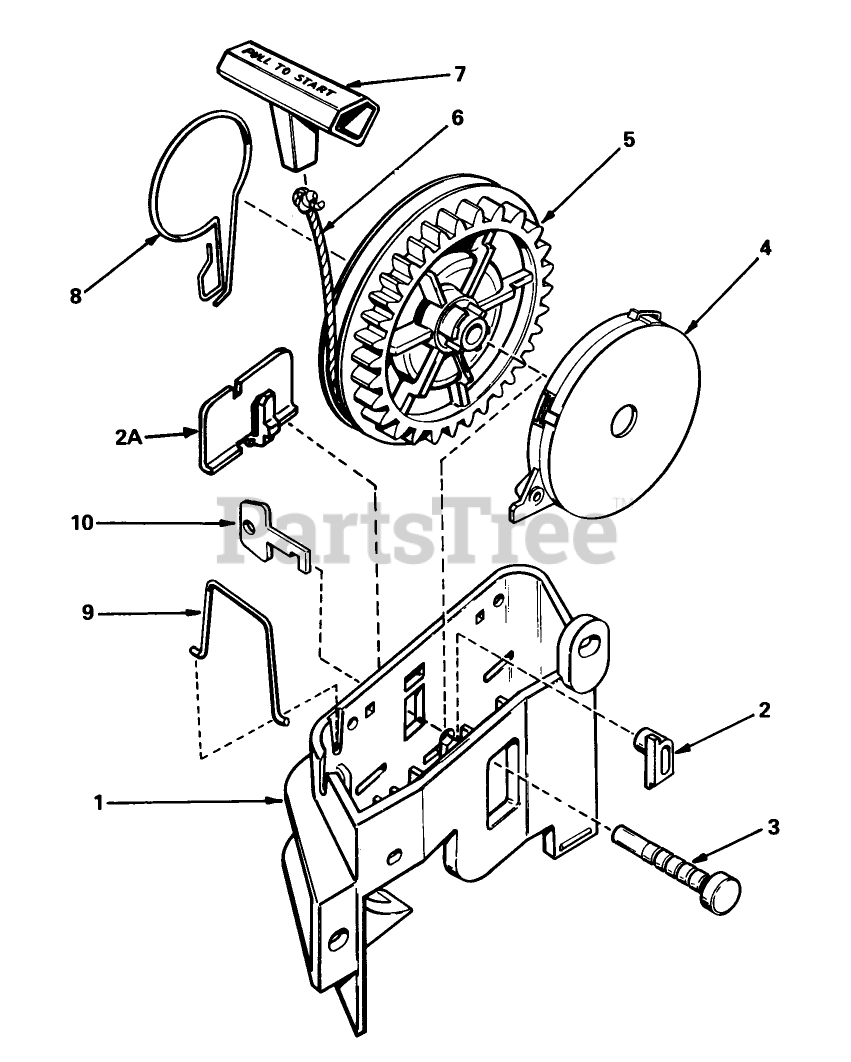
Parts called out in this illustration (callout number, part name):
1	Bracket Starter
2	Pawl, Locking Not used on all engine models)
2A	Clip, Starter Bracket (Used On Starters Not Equipped With Pawl, Ref. No. 2)
3	Pin-Pulley
4	Spring Assy., Rewind (Incl. Ref. #3)
5	Pulley
6	Rope Starter (Length 65" 9/64" Dia.)
7	Handle-Starter
8	Brake
9	Clip-Rope
10	Key (Not Used On All Engine Models
